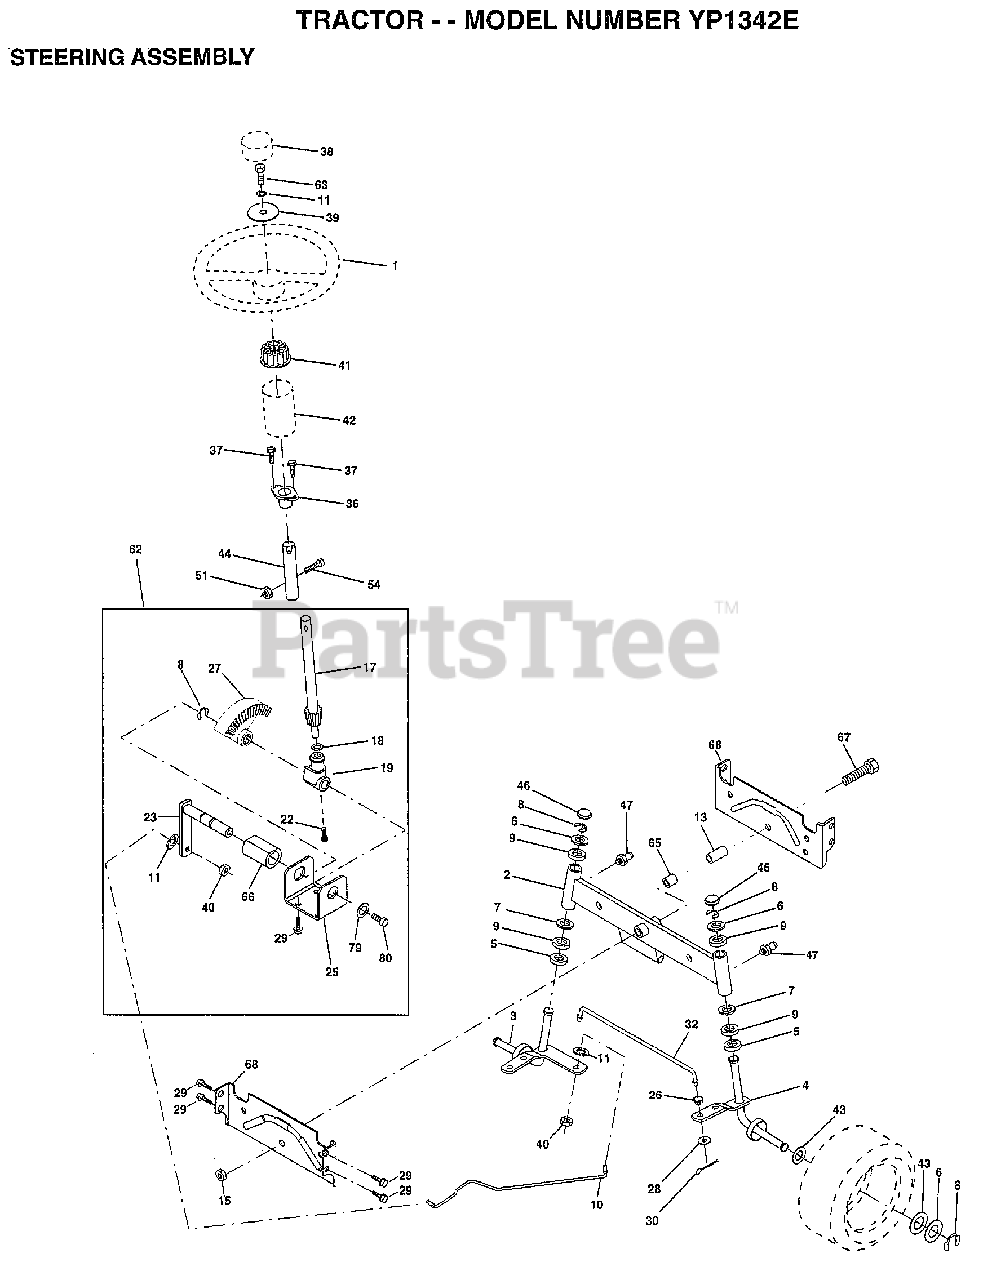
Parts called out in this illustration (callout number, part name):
1	WHEEL STR AYP BLK
2	AXLE ASM
3	SPINDLE.ASM.LH
4	"SPINDLE ASM,RH"
5	WASHER .T
6	WASHER
7	WASHER
8	RING
9	COL. SRTG. BEAR.
10	DRAGLINK-STAMPED
11	LOCKWASHER
13	BEARING AXLE
15	"NUT-LOC,FLANGE LT"
17	SHAFT ASM STEERIN
18	THRUST WASHER
19	SUPPORT.SHAFT.STEER
22	SCREW.HX.WSH.HD
23	SHAFT.ASM.PITMAN
25	BRKT-STEERING
26	BUSHING.DRAGLINK
27	GEAR SECTOR
28	WASHER
29	SCREW
30	COTTER PIN
32	TIE ROD
36	BUSHING.STEERING
37	"SCREW-TT,10-32 FL"
38	CAP STEER AYP
39	WASHER T
40	GRIPCO NUT
41	ADAPTER LT
42	BOOT.STEER.PL
43	WASHER
44	EXT SHAFT STEERIN
46	CAP
47	ZERK M
51	NUT
54	BOLT
62	KIT.STEER.ASM
63	BOLT
65	SPACER AXLE
66	"BEARING-ARM,PITMA"
67	BOLT
68	BRACE AXLE
79	WASHER
80	BOLT.HX.NYLON3/8-16X3/
